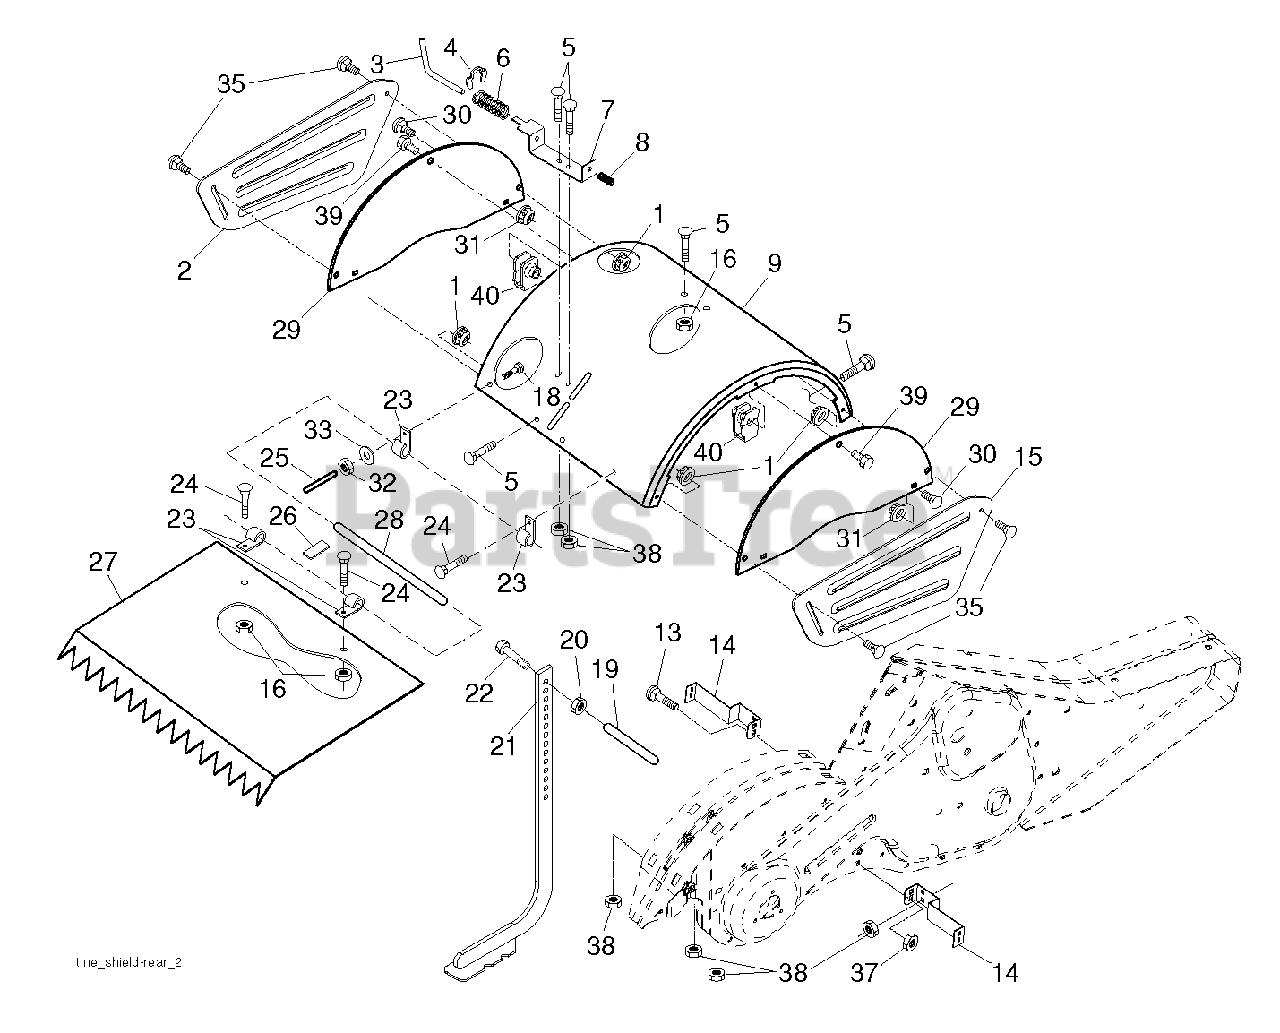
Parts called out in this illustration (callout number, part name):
1	NUT.FLANGE.5/16
3	STAKE PIN TI
4	RING, KLIP
5	BOLT, RDHD SQNK 5/16-18 X 3/4
6	SPRING TI
7	Latch Stake Bracket, 3 20 Black
8	SPRING CRT
13	BOLT.CARRIAGE.5/16-18
14	BRACKET.TINE.SHIELD.TILLER.BLA
16	NUT T
20	NUT.HEX.3/8-16UNC
22	BOLT.375-16
23	HINGE CRT
25	VINYL CAP TI
26	PAD IDLER TI
28	PIN.HINGE.TILLER
29	RP.SHIELD.ASM.PNT.SIDE.RED
30	BOLT.CARRIAGE.5/16-18X
31	LOCKNUT-FLANGE 5/16-18
32	NUT
33	LOCKWASHER
35	BOLT
37	LOCKNUT-FLANGE 5/16-18
38	NUT
39	BOLT.HEX.HD.WASHER.5/16-18X.75
40	NUT, SPEED 5/16-18
